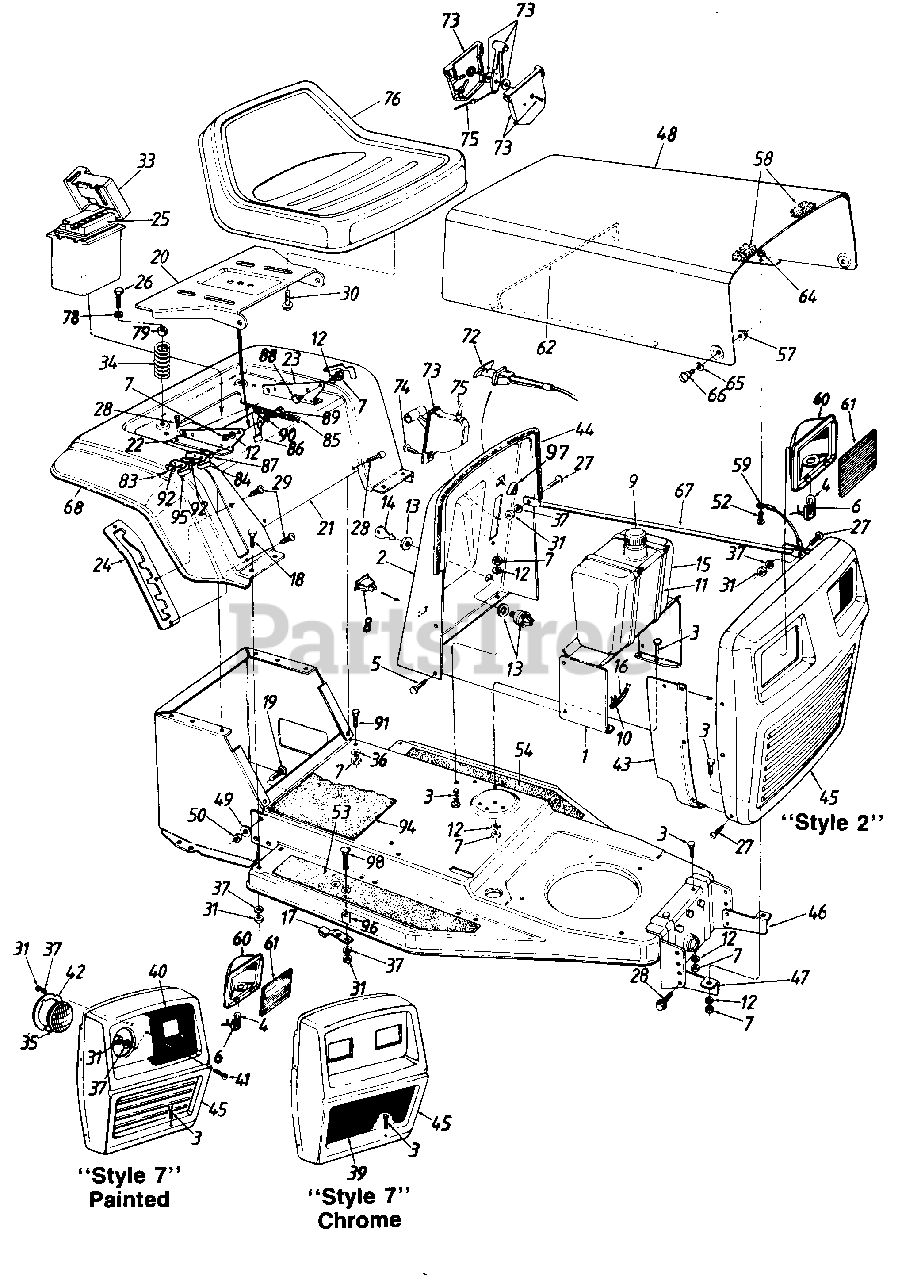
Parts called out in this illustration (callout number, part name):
1	Dash Panel Support Brkt.
4	Bulb
5	Hex AB-Tap Scr. 1/4 x .62"
6	Socket
7	Hex Nut 5/16-18 Thd.
8	Light Switch
9	Gas Cap
10	Hose Clamp
11	Cable Tie
12	L-Wash. 5/16" I.D.
13	Ignition Switch
14	Ignition Key
15	Fuel Tank
16	Gas Line 15" Long
17	Blade Brake Ass'y.
18	Carriage Bolt 1/4-20 x .62"
19	Ribbed Neck Bolt 3/8-24 x .8"
20	Seat Pivot Brkt.
25	Battery
26	Hex Self-Tap Screw 5/6-18 x 1.25" Lg.
27	Truss Mach. Scr. 1/4-20 x .75" Lg.
28	Hex AB-Tap Scr. 5/16 x .75" Lg.
29	Torx Mach. AB-Tap Scr. 1/4 x .62" Lg.
30	Hex Self-Tap Scr. 3/8-16 x .75" Lg.
31	Hex Nut 1/4-20 Thd.
33	Battery Box w/Cover
34	Compression Spring
35	Headlight
36	Bell-Wash. 5/16" I.D.
37	L-Wash. 1/4" I.D.
39	Grille Insert
40	Bezel
41	C-Sunk Mach. Scr. 1/4-20 x 1.5"
42	Headlight Retainer
44	Trim Strip 31" Lg.
47	Grille Mtg. Brkt.-R.H.
50	Hex L-Nut 3/8-24 Thd.
52	Truss Mach. Scr. #10-24 x .5" Lg.
53	Foot Pad-R.H.
54	Foot Pad-L.H.
57	Lock Nut 1/4-28 Thd.
58	Foam Strip
59	Hood Stop
60	Headlight Housing
61	Lens
62	Hood Spring
64	Hex Sems Nut #10-24 Thd.
65	Spr. Wash. .39" I.D. x .62" O.D.
66	Shld. Bolt
67	Grille Support
68	Trim Strip 81" Lg.
72	Choke Control
73	Throttle Control Box
74	Truss AB-Tap Scr. #10 x .5"
75	Throttle Wire
76	Seat Assembly
78	Fl-Wash. .344" I.D. x .88" O.D.
79	Bushing
83	Hex Tap Scr. #8 x .5" Lg.
84	Safety Switch
85	Ext. Spring 5.31" Lg.
86	Seat Lift Brkt.
87	Insulator Boss Plate
88	Shld. Bolt .437" Dia. x .162" Lg.
89	Shld. Bolt .437" Dia. x .268" Lg.
90	Spr. Wash. .445" I.D. x .75" O.D.
91	Hex Wash. Hd. Scr. 5/16-18 x .62" Lg
92	Insulator Plate
94	Center Foot Pad
95	Safety Switch
96	Spacer
97	Retainer Clip
98	Carriage Bolt 1/4-20 x 1.25" Lg.
